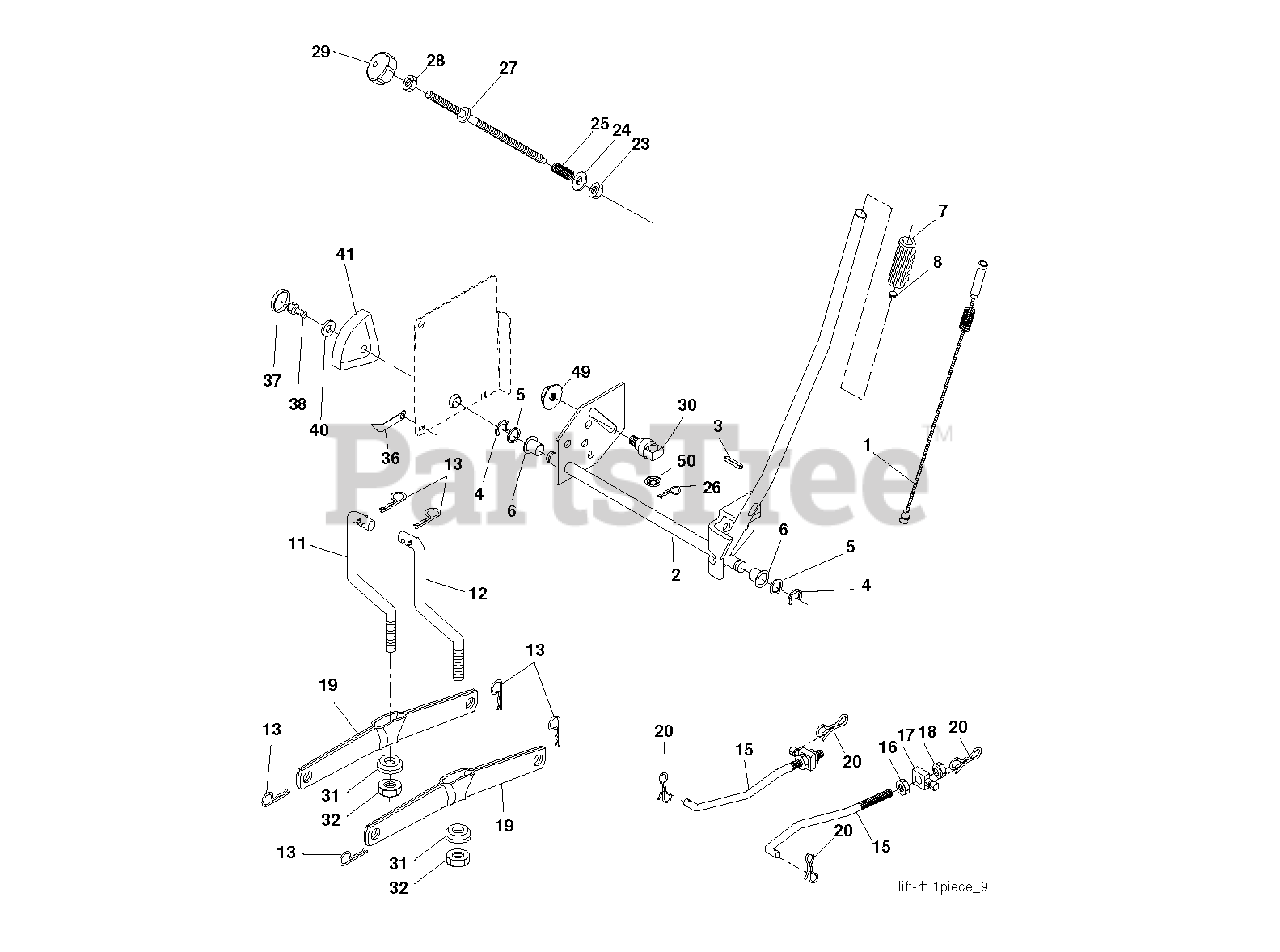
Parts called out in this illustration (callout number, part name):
1	PLUNGER.ASM.LIFT.LVR.BLK.17.32
2	SHAFT ASM R HANDLE
3	PIN GROOVE
4	RETAINING RING LT
6	BEARING.NYLON
7	GRIP HANDLE
8	PLUNGER BUT KIT
11	LINK
12	LINK
13	RETAINER-SPRNG RB
15	LINK.SUSPENSION.FRONT
16	NUT
18	NUT
19	ARM.REAR.SUSPENSION
20	PIN.COTTER.7/16.BOW TI
25	SPRING**
26	RETAINER CLIP
27	ROD ADJ LIFT
28	NUT
29	KNOB INF 3/8-16
31	BEARING.PIVOT.LIFT
32	NUT CROWNLOCK 3/8-24
36	POINTER, HEIGHT INDICATOR
37	PLUG,HOLE
38	SCREW 5/16-18X1
41	HEIGHT INDICATOR
49	NUT
50	NUT PUSH M
